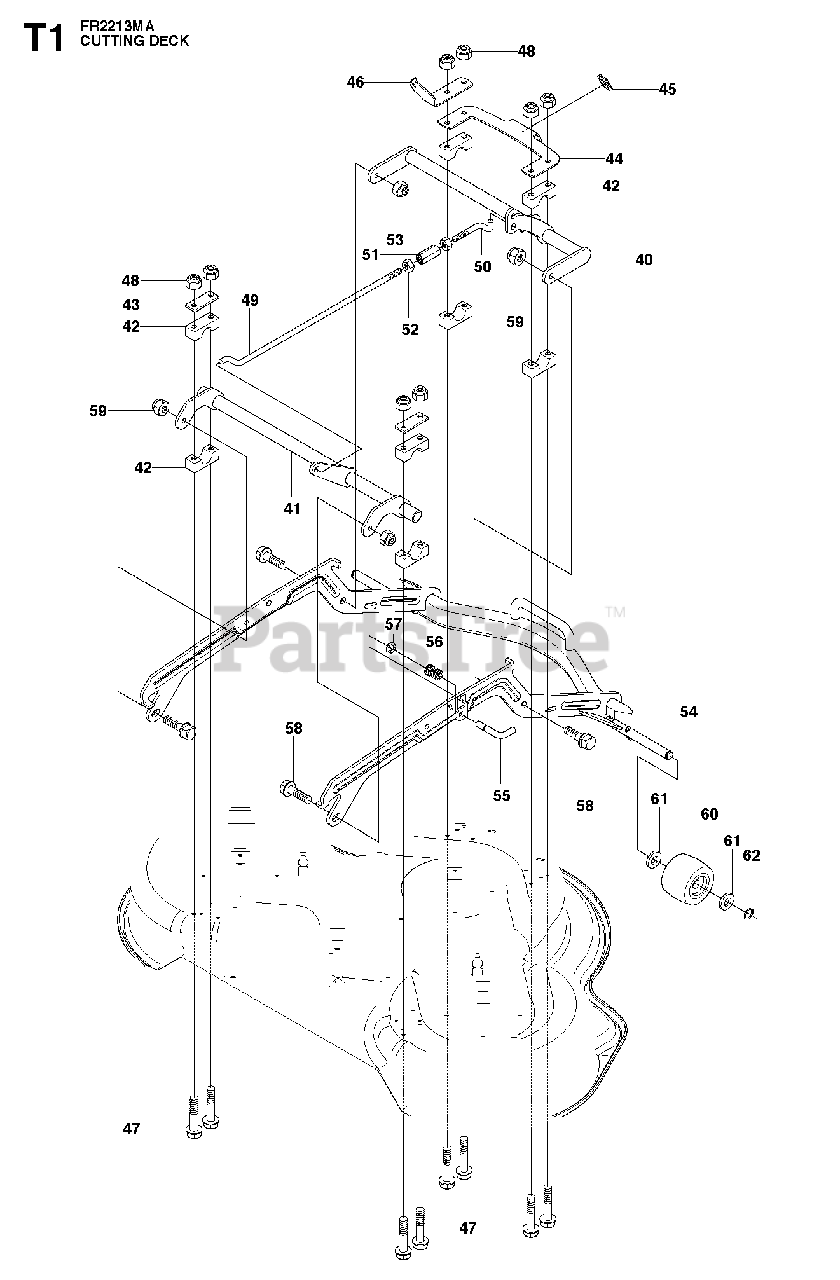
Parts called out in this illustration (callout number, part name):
48	LOCKNUT M8
59	LOCKNUT M8
60	DECK ROLLER, FRONT
62	RETAINING RING SGA 15
